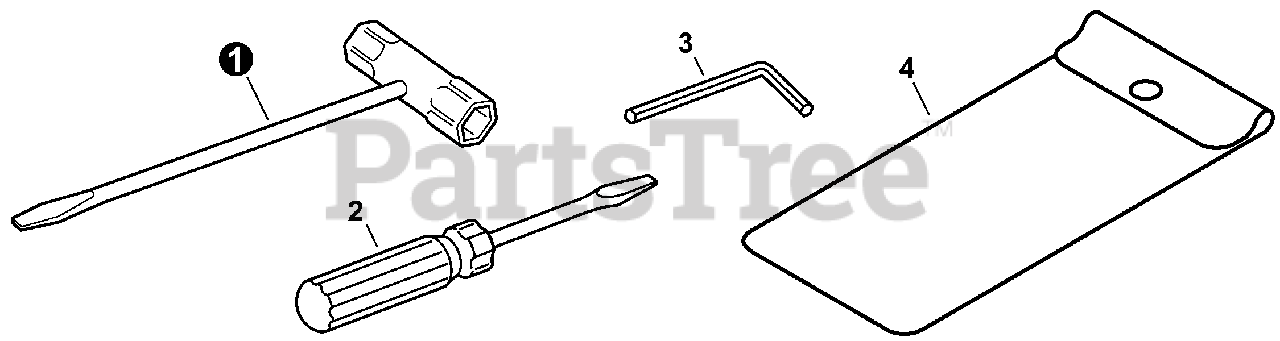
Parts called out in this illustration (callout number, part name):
1	T-WRENCH 13×19 L= 180
2	SCREWDRIVER 50MM
3	WRENCH, ALLEN 4MM
4	BAG, TOOL
